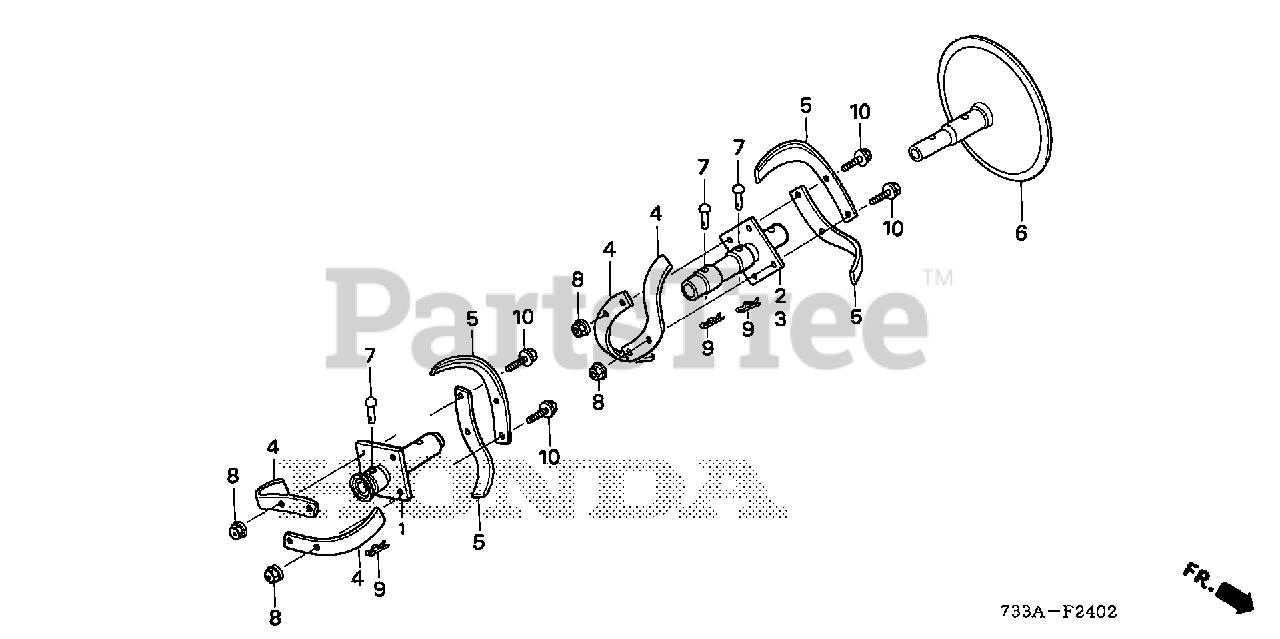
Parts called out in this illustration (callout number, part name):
1	PIPE (INNER)
2	PIPE, R. (OUTER)
3	PIPE, L. (OUTER)
4	TINE A, ROTARY
5	TINE B, ROTARY
6	DISK, SIDE
7	PIN (10X53.5)
8	NUT, FLANGE (10MM)
9	PIN, LOCK (10MM)
10	BOLT, FLANGE (10X25)
